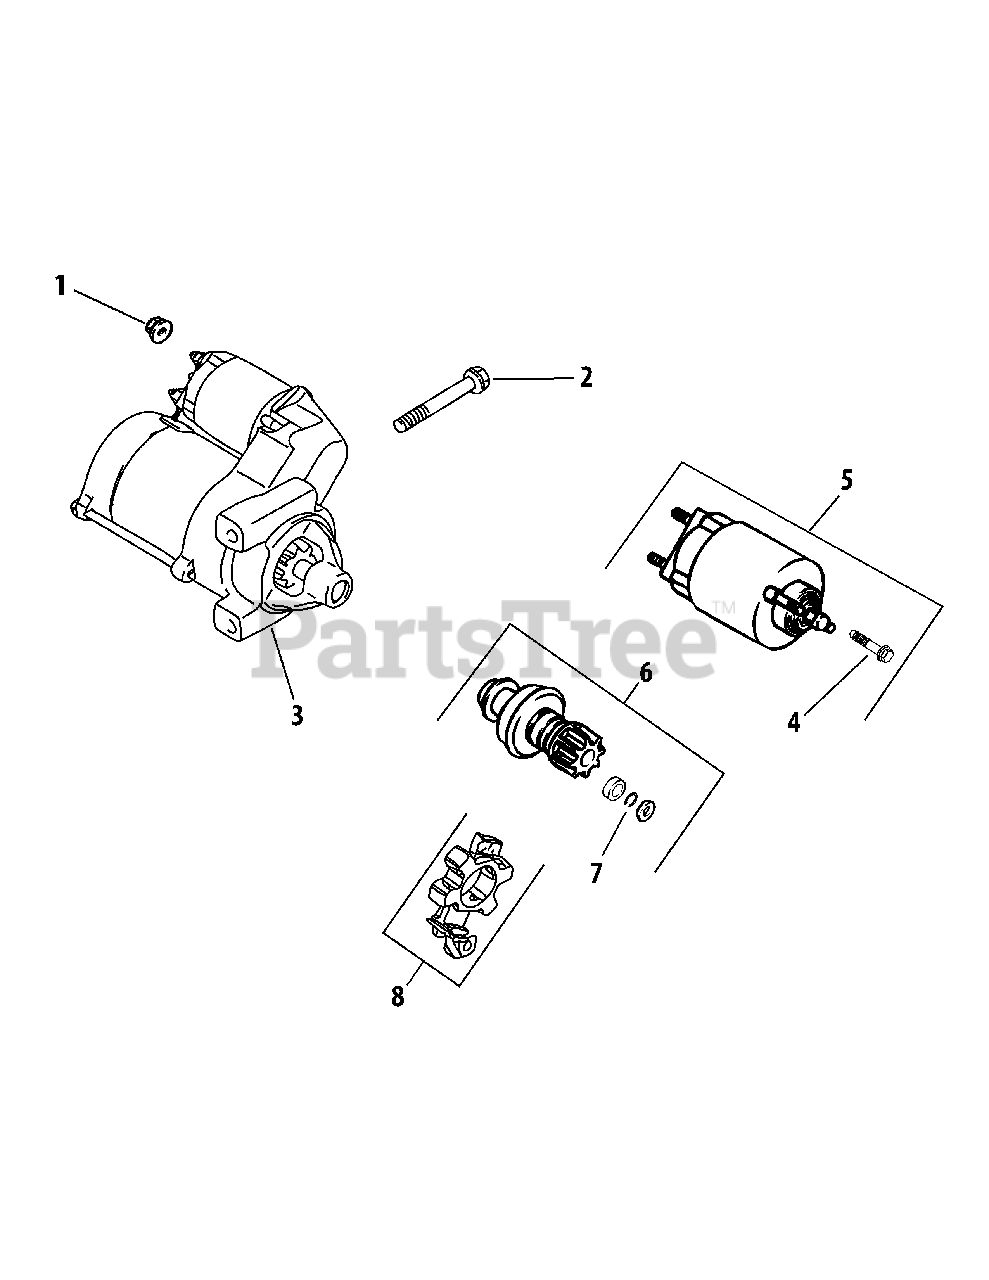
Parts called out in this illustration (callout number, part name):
1	Nut, Hex Flange M8 x 1.25"
2	Screw, Hex Flange M8 x 1.25 x 80
3	Starter, Solenoid Shift Assembly (Includes 4-8)
4	Screw, External Torx Hd.
5	Kit, Solenoid
6	Kit, Pinion Drive (Includes 7)
7	Ring, Retainer
